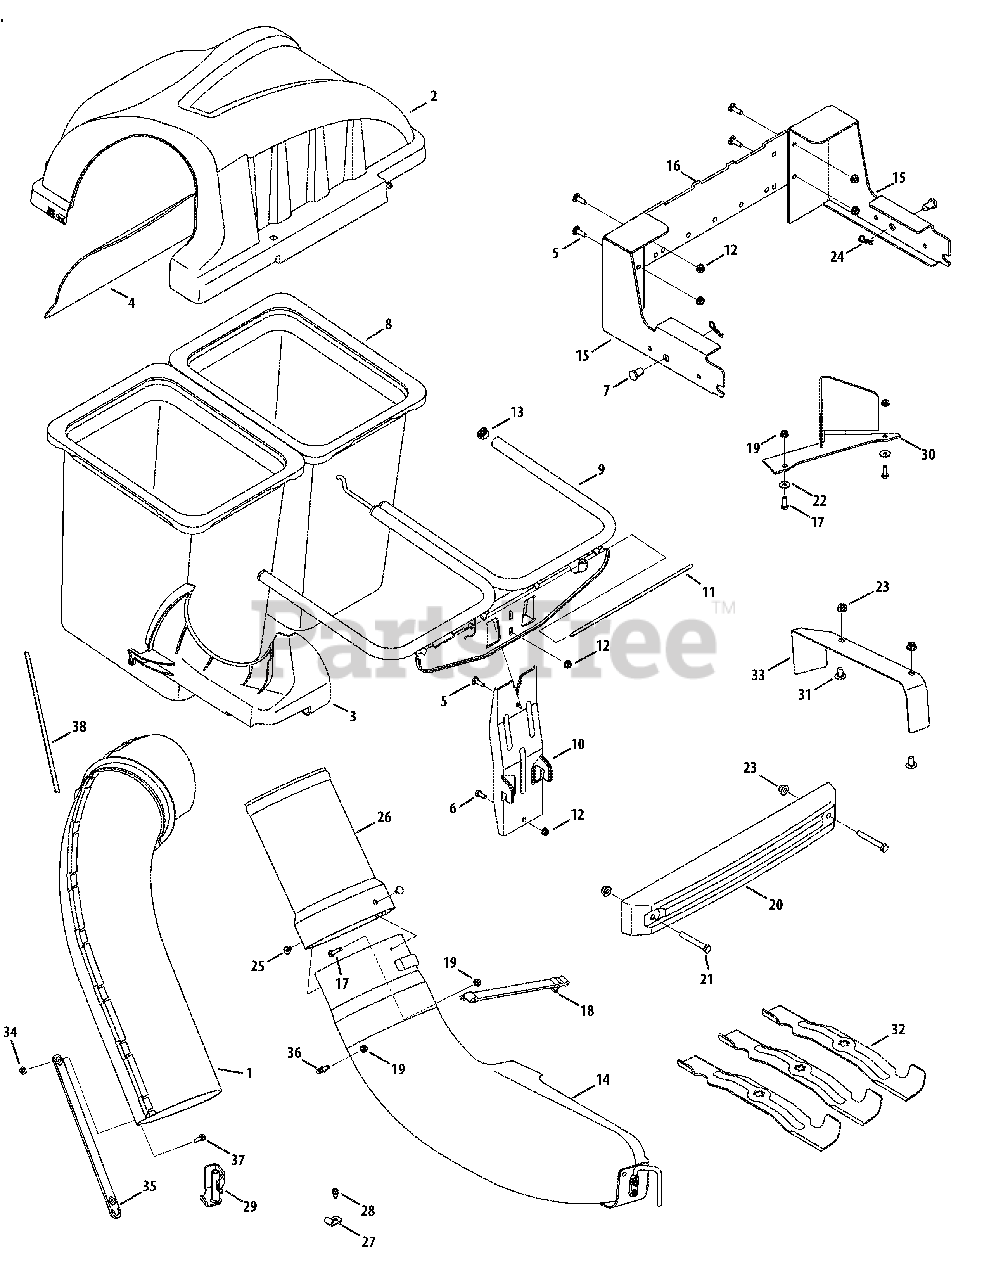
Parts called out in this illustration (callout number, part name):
1	Upper Chute Assembly
2	Twin Bagger Cover Assembly
3	Upper Chute Support
4	Bagger Cover Screen
5	Carriage Screw, 5/16-18 x 1.00"
6	Hex Head Screw, 5/16-18 x .75"
7	Clevis Pin, .50" Dia.
8	Grass-bag Assembly
9	Twin Bag Support Assembly
10	Vertical Support Bracket
11	Cover Hinge Pin
12	Flange Lock Nut, 5/16-18
13	End Plug
14	Discharge Chute Elbow
15	RZT Hitch Bracket Kit (RH & LH)
16	Universal Cross Bracket
17	Hex Head Screw, 1/4 - 20 x .75
18	Chute Strap
19	Flange Lock Nut, 1/4 - 20
20	Bagger Weight
21	Hex Head Screw, 3/8 - 16 x 2.75
22	Belleville Washer
23	Flange Lock Nut, 3/8 - 16
24	Cotter Pin, .080 x 1.5625 Internal
25	Ratchet Clip, .250
26	Bagger Chute Adapter, 8 x 13.5
27	Retainer Hook Bracket
28	Self-Tap Screw, 1/4-20 x .500
29	Chute Stop Bracket
30	Deck Baffle, 50"
31	Carriage Bolt, 3/8-16 x 1.00
32	Bagging Blade, 17.90 Lg. Star
33	Chute Discharge Plate
34	Flange Lock Nut, 1/4-20
35	Chute Strap
36	Grass-catcher Pin
37	Machine Screw, 1/4-20
38	Adhesive Strip
